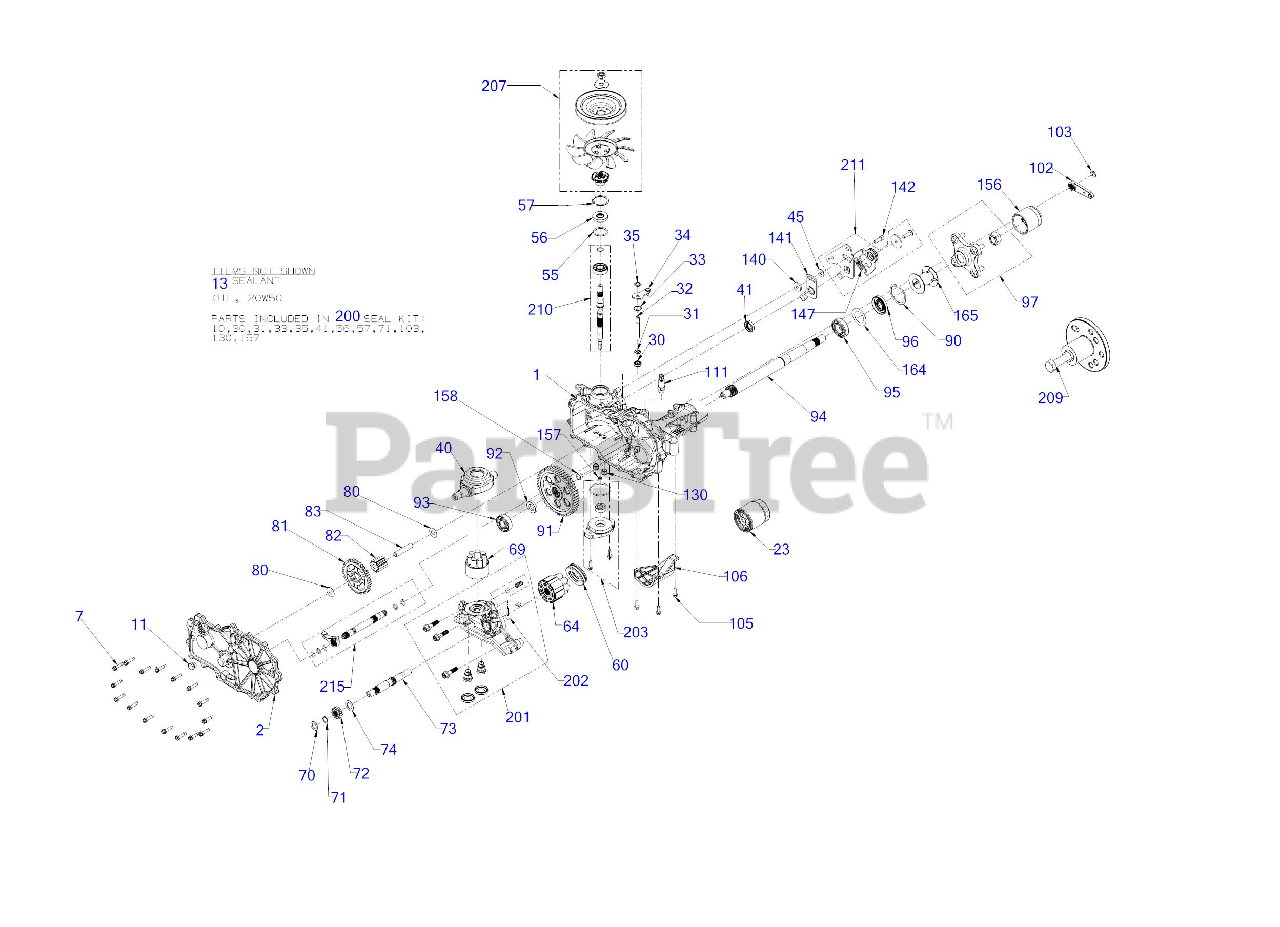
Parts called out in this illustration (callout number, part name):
1	KIT - HOUSING MAIN RH CNTL
2	KIT - SIDE COVER RH
7	SCREW-WASHER HEAD
11	VENT PLUG
13	SEALANT-HOUSING
23	FILTER-OIL
30	SEAL-LIP .375
31	RETAINING RING
32	BYPASS RODS
33	RETAINING RING
34	ARM-BYPASS
35	RETAINING RING
40	SWASHPLATE-TRUNNION
45	FLAT WASHER
55	WASHER 1.23X1.56X
57	RETAINING RING
60	THRUST BEARING
64	CYLINDER BLOCK ASSEMBLY KIT
69	BLOCK KIT
70	FLAT WASHER
71	RETAINING RING
72	GEAR - 13 TOOTH STEEL
73	MOTOR SHAFT
74	MOTOR SHAFT WASHER
81	GEAR - 46 TOOTH
82	GEAR-11 T
83	PIN-JACKSHAFT
90	RETAINING RING
91	GEAR - 54 TOOTH
92	SPACER .75X1.32X.257
93	BALL BEARING
94	AXLE SHAFT
95	BALL BEARING
97	HUB KIT-4 BOLT
102	BRAKE LEVER
103	RETAINING RING EXT .438
106	GUARD-FILTER (RH)
111	FITTING-STEERINGT BARB
130	TUBE-CHARGE TRIPLE O-RING
140	SPACER .32 x 1.005 x .179
141	ARM-NEUTRAL (RH)
142	SCREWS KIT-RTN
147	EXTENSION SPRING
157	KIT-GEROTOR SEAL
158	MAGNET-RING
165	TUBE-AXLE 2.03
200	KIT - SEAL
201	CENTER SECTION KIT (RH)
202	KIT-CHARGE RELIEF
203	CHARGE KIT
207	FAN & PULLEY KIT
209	PULLER KIT-HUB
210	INPUT SHAFT KIT
211	KIT - RETURN CW
215	INBOARD KIT
